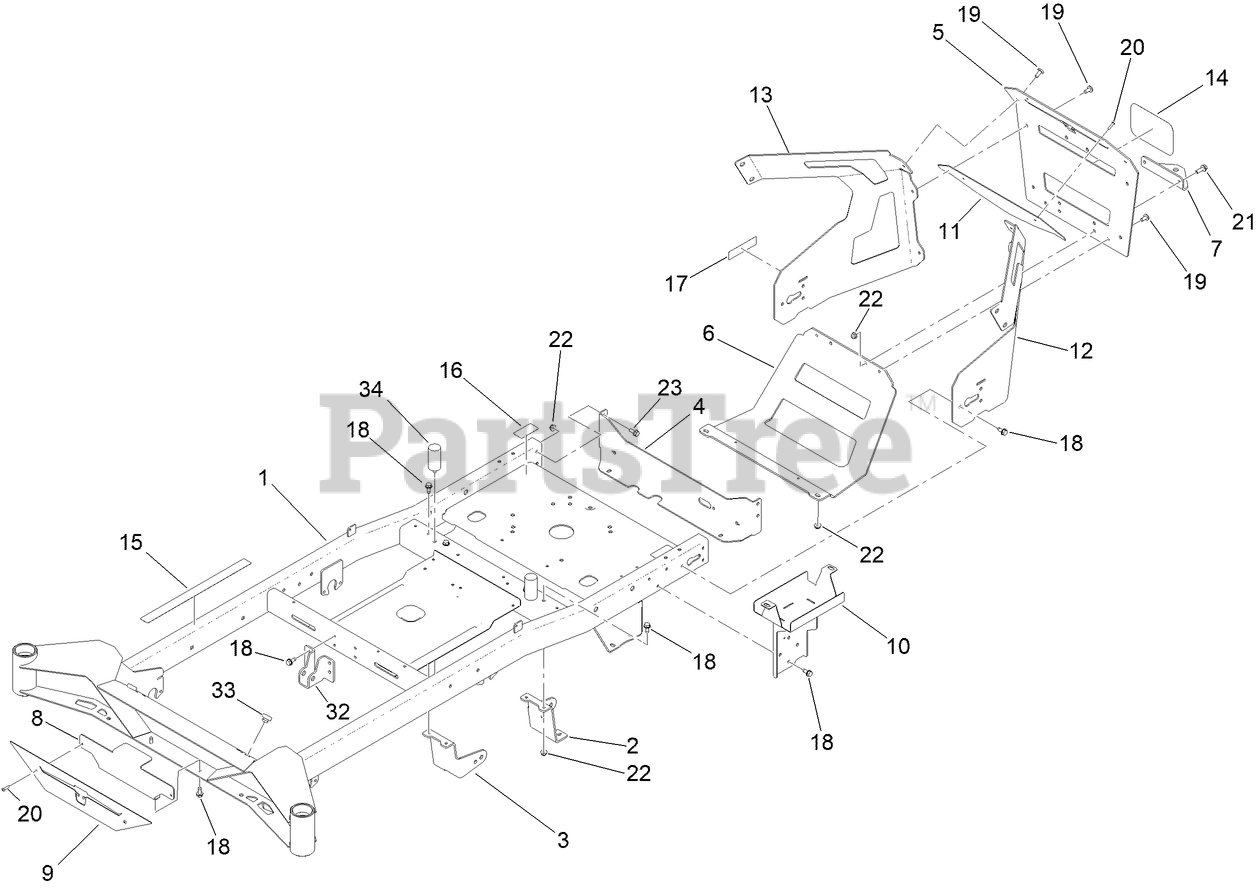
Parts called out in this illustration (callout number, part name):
1	SERVICE ASM-FRAME, TITAN
2	MOUNT-DRIVE, LH
3	MOUNT-DRIVE, RH
4	PLATE-MOUNT
5	GUARD-ENGINE
6	GUARD-MUFFLER
7	BRACKET-HITCH
8	PLATE-BACKER
9	LOGO-PLATE-FRONT
10	WA-BATTERY MOUNT
11	PLATE-BACKER
12	GUARD-ENGINE LH
13	GUARD-ENGINE-RH
14	DECAL
15	DECAL-WARNING
16	DECAL-BYPASS
17	DECAL-SPARK ARRESTER
18	SCREW-HWHTF
20	RIVET-TRIFOLD
21	SCREW-HHF
22	NUT-HF
23	SCREW-HHF
32	BRACKET-MOUNT DAMPER, LOWER
33	BUMPER-RUBBER
34	BUMPER-RUBBER
